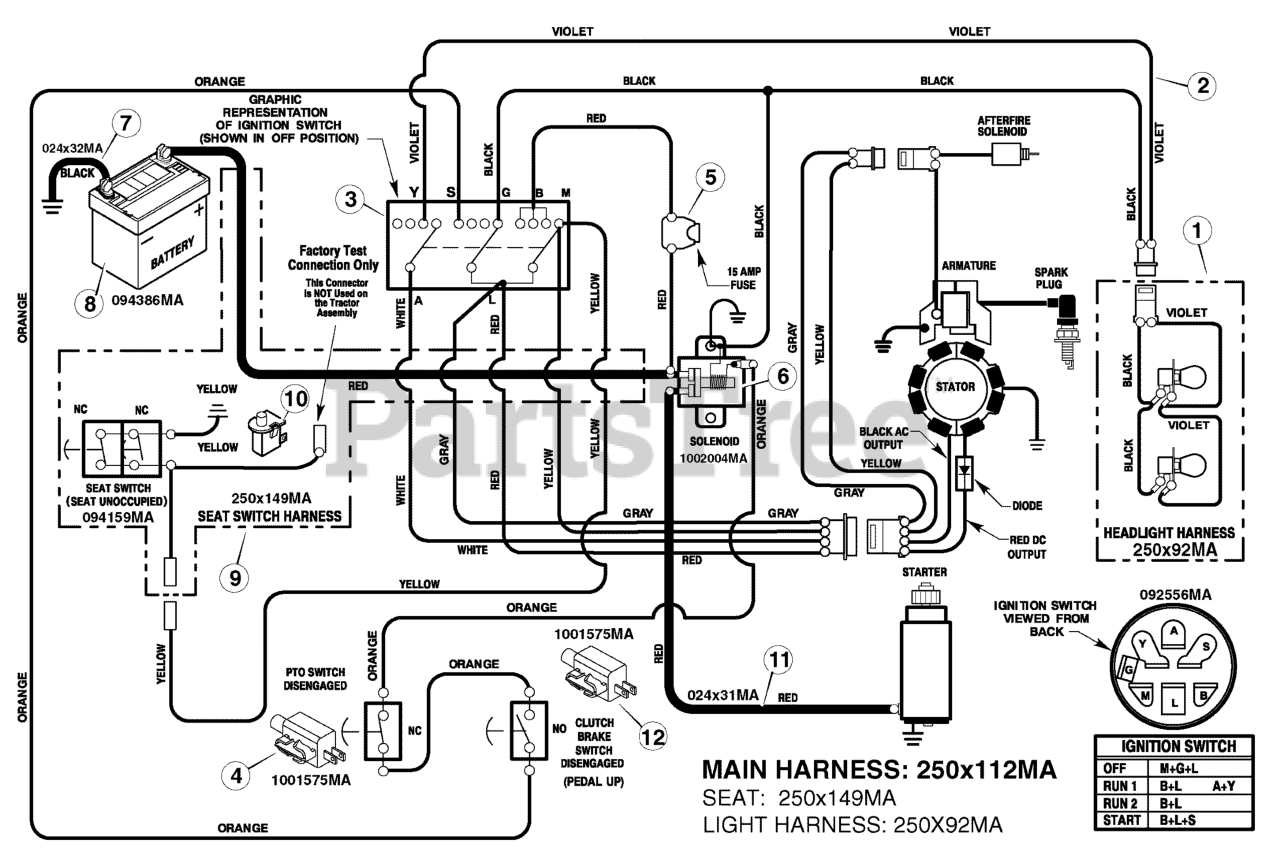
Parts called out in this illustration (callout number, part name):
1	Harness, Light Wire
2	Harness, Chassis Wire
3	Switch, Ignition
4	Switch, Limit (PTO)
6	Solenoid
7	Cable, Battery Ground
8	Battery
9	Harness, Seat Switch Wire
10	Switch, Seat Sensor
12	Switch, Select Reverse / Clutch Brake
